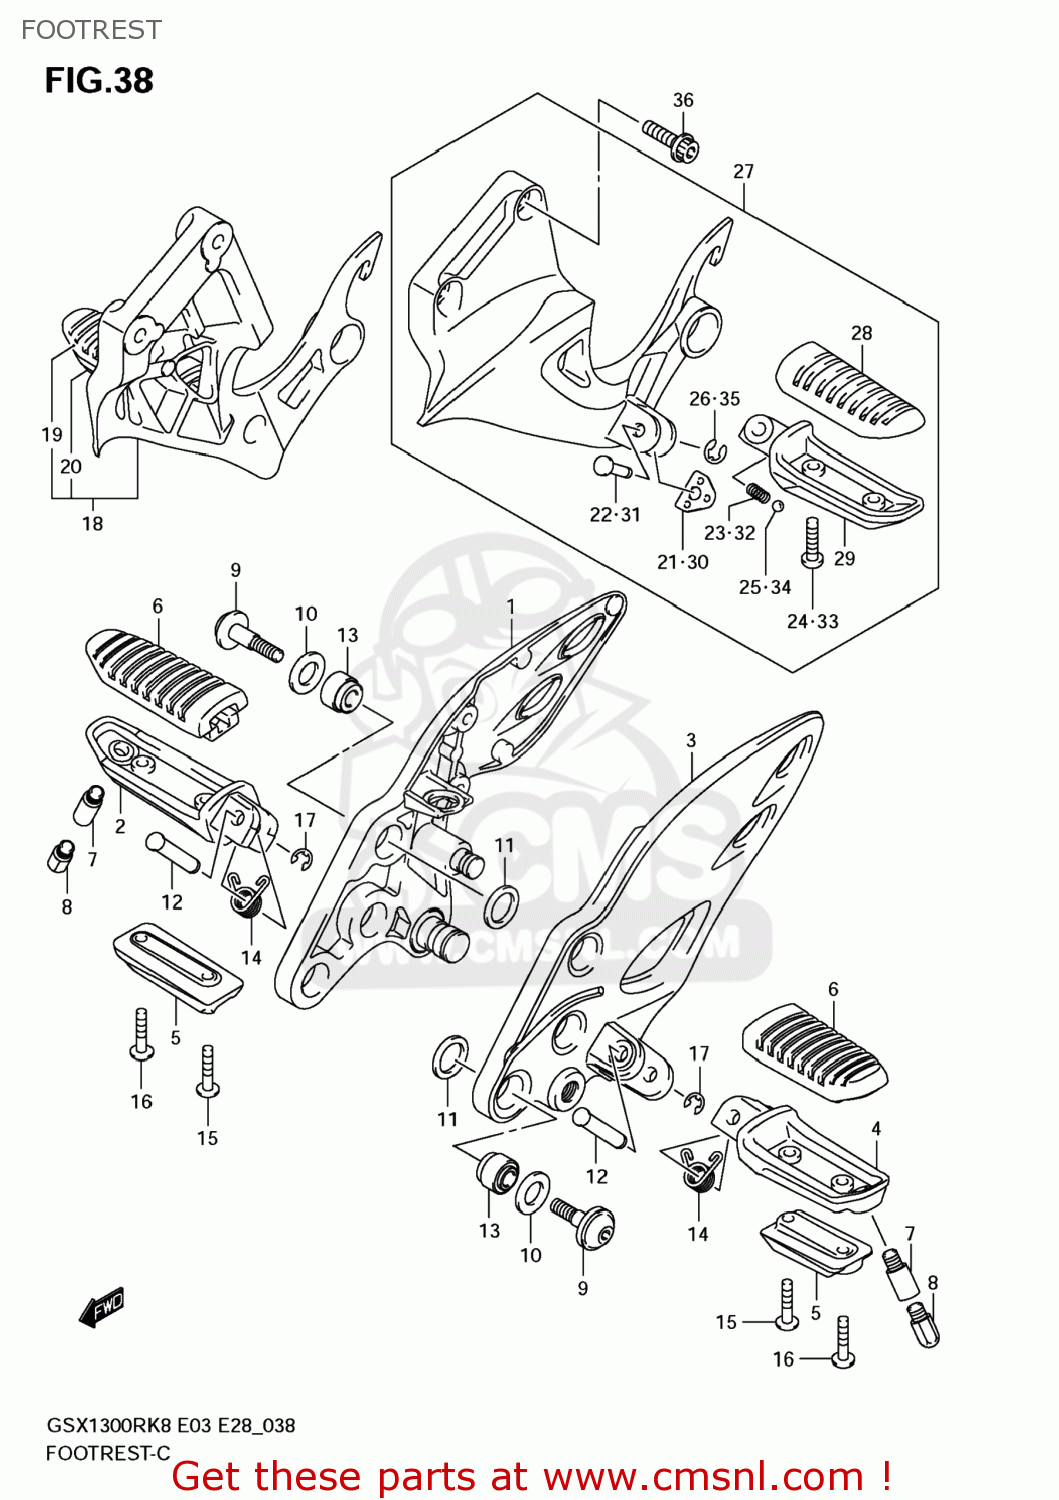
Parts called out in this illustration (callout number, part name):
1	BRACKET,FR FOOTREST,R
2	BAR,FR FOOTREST,R
3	BRACKET,FR FOOTREST,L
4	BAR,FR FOOTREST,L
5	BALANCER,FR FOOTREST
6	RUBBER,FOOTREST BAR
7	SENSOR,FOOTREST
8	SENSOR,FOOTREST
9	BOLT(8X30)
10	WASHER(13.7X24X2)
11	WASHER(17.2X24X2.2)
12	PIN
13	BUSH(8.4X20X16)
14	SPRING
15	SCREW
16	SCREW
17	E RING
18	FOOTREST ASSY,PILLION,R
19	RUBBER,FOOTREST
20	BAR,PILLION FOOTREST,R
21	PLATE,PILLION FOOTREST
22	PIN
23	SPRING
24	SCREW
25	BALL
26	E RING
27	FOOTREST ASSY,PILLION,L
28	RUBBER,FOOTREST
29	BAR,PILLION FOOTREST,L
30	PLATE,PILLION FOOTREST
31	PIN
32	SPRING
33	SCREW
34	BALL
35	E RING
36	BOLT(8X30)
